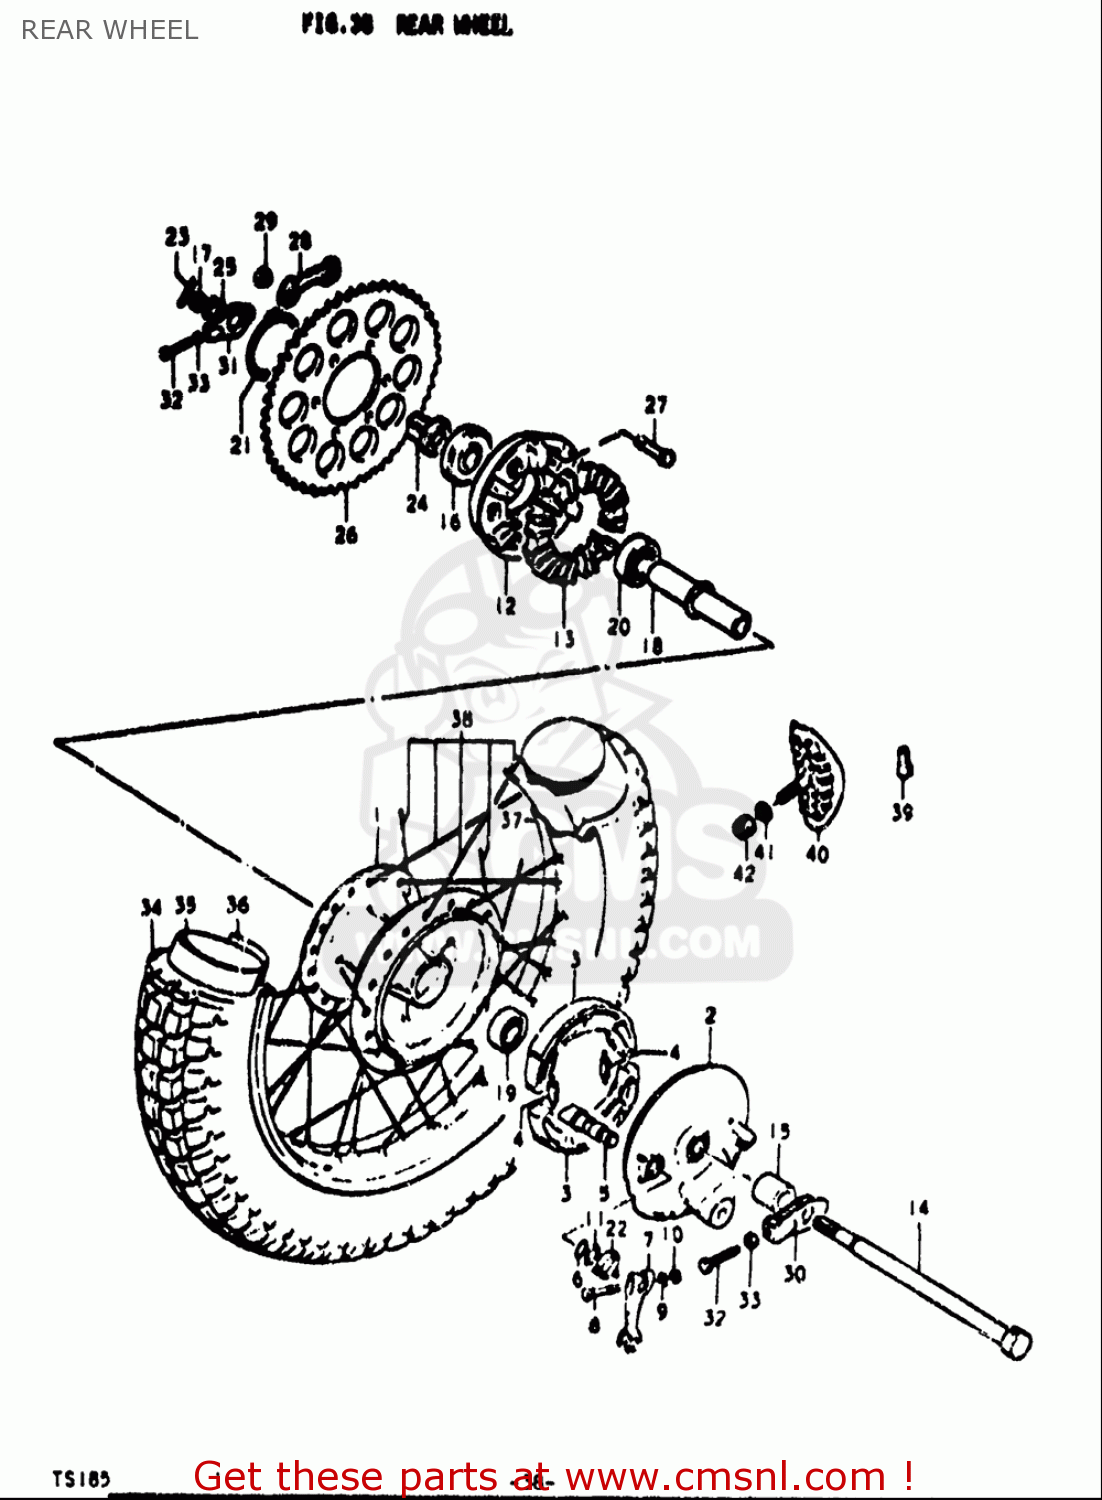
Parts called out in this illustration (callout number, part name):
4	SPRING(L:35.8)
5	CAM,FR BRAKE
6	O RING(D:2.5,ID:11.4)
8	BOLT(6X31)
9	WASHER
10	NUT
11	WASHER(12.5X20X1)
13	ABSORBER,RR WHEEL HUB SHOCK
14	AXLE,REAR
15	SPACER(15.2X22X26)
16	SPACER,RR AXLE,L
17	NUT 12MM
19	BEARING
20	B1 15X42X13 BEA
21	CIRCLIP
22	SPRING
23	PIN
24	SPACER,CHAIN ADJUSTER,L
25	NUT
26	SPROCKET,RR
27	BOLT(8X32)
28	WASHER
30	ADJUSTER,CHAIN
31	ADJUSTER,CHAIN,L
32	BOLT(6X38)
33	NUT
35	TUBE ASSY,INNER
36	PROTECTOR,INNER TUBE
39	BALANCER,WHEEL (30G)
40	STOPPER,BEAD
41	WASHER
42	NUT
